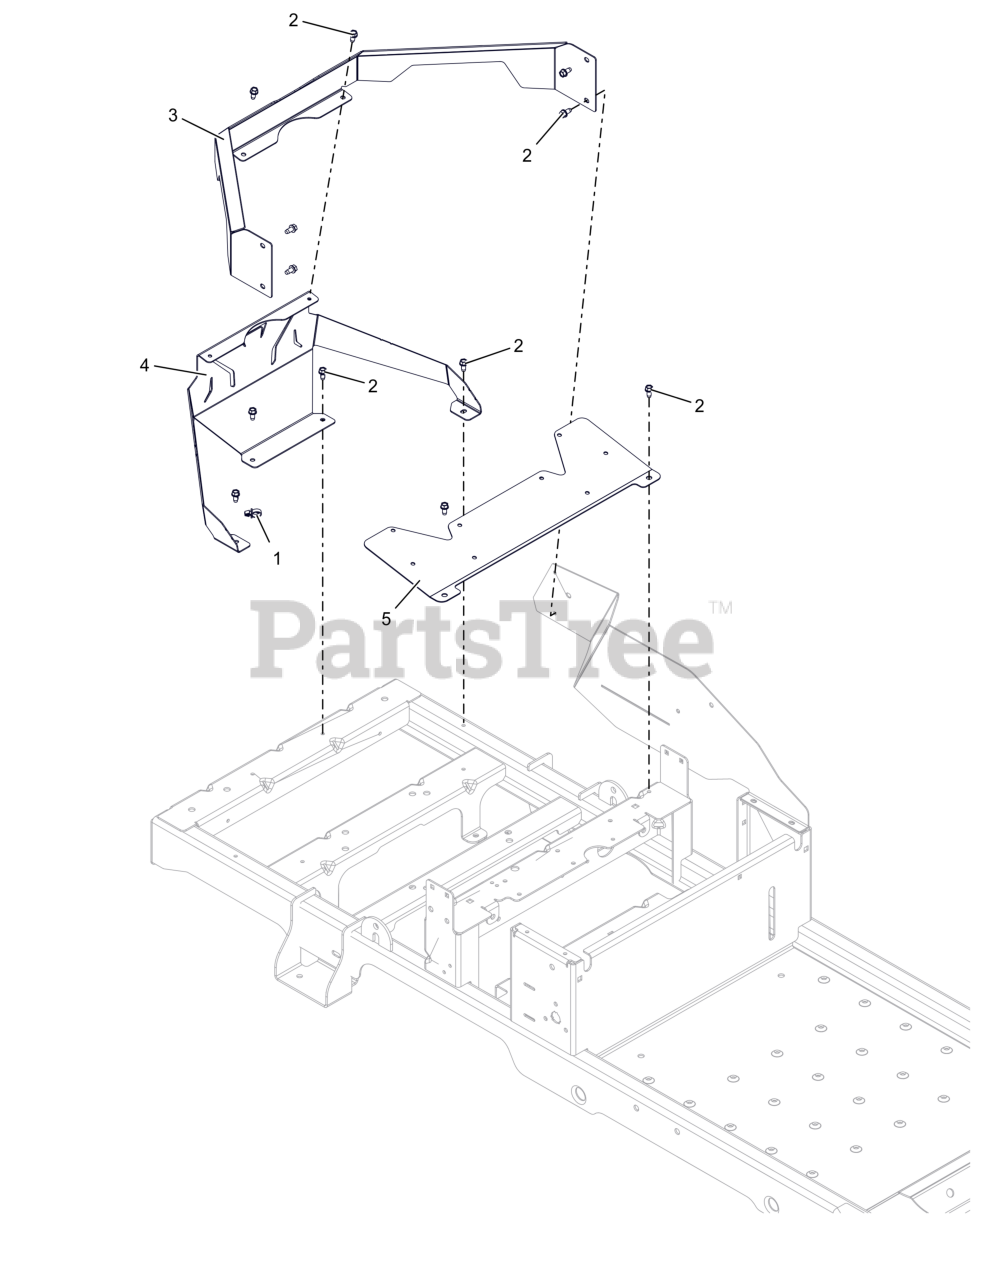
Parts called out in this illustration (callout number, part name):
1	ROUTING CLIP (1/2" ID)
2	SCR-TAP .25-20X.50 HWH ZCC
3	WRAP, REAR -TOP,GRAVELY (RED)
4	WRAP, REAR ,GRAVELY ZT (BLACK)
5	PLATE, FAN W/DECAL
